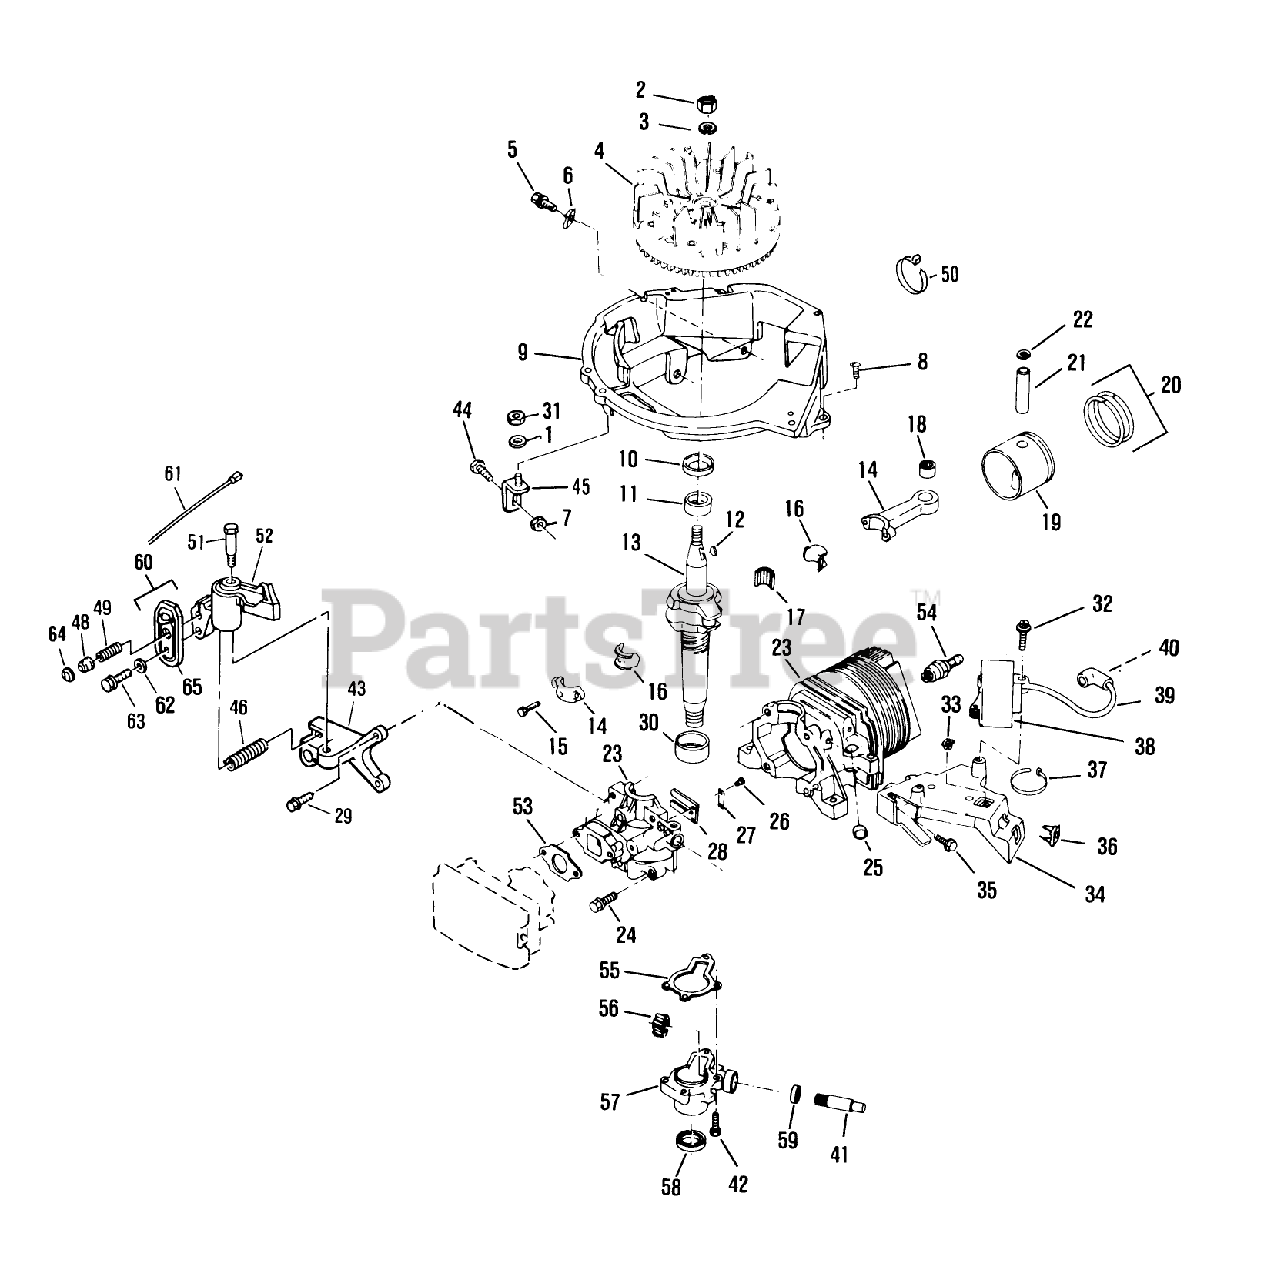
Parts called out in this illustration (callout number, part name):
1	WASHER S
2	NUT
4	FLYWHEEL ASSY F
5	SCREW-SEMS
7	NUT-LOCK F
8	SCREW F
9	BASE SHROUD F
10	SEAL-OIL
11	BEARING V
12	KEY
15	SCREW-HSH
16	LINER ASM
17	BEARING-NEEDLE
18	BEARING AY F
22	RING-RETAINING
24	SCREW S
25	PLUG-CORE VF
26	SCREW-HH
27	PLATE-BACKUP, REED
30	BEARING S
31	LOCKNUT E
33	NUT-CLIP
34	BRACKET S
36	NUT-CLIP
39	HT LEAD&COVER XEV
41	DR SHAFT,PTO S
43	BRACKET-BRAKE F
44	BOLT F
46	SPRING-BRAKE
48	ACTUATOR-LEVER, BRAKE
49	SPRING
53	GASKET CARB S
55	GASKET S
58	SEAL-OIL
59	SEAL S
61	WIRE LEAD AY F
62	WASHER
64	RETAINER S
